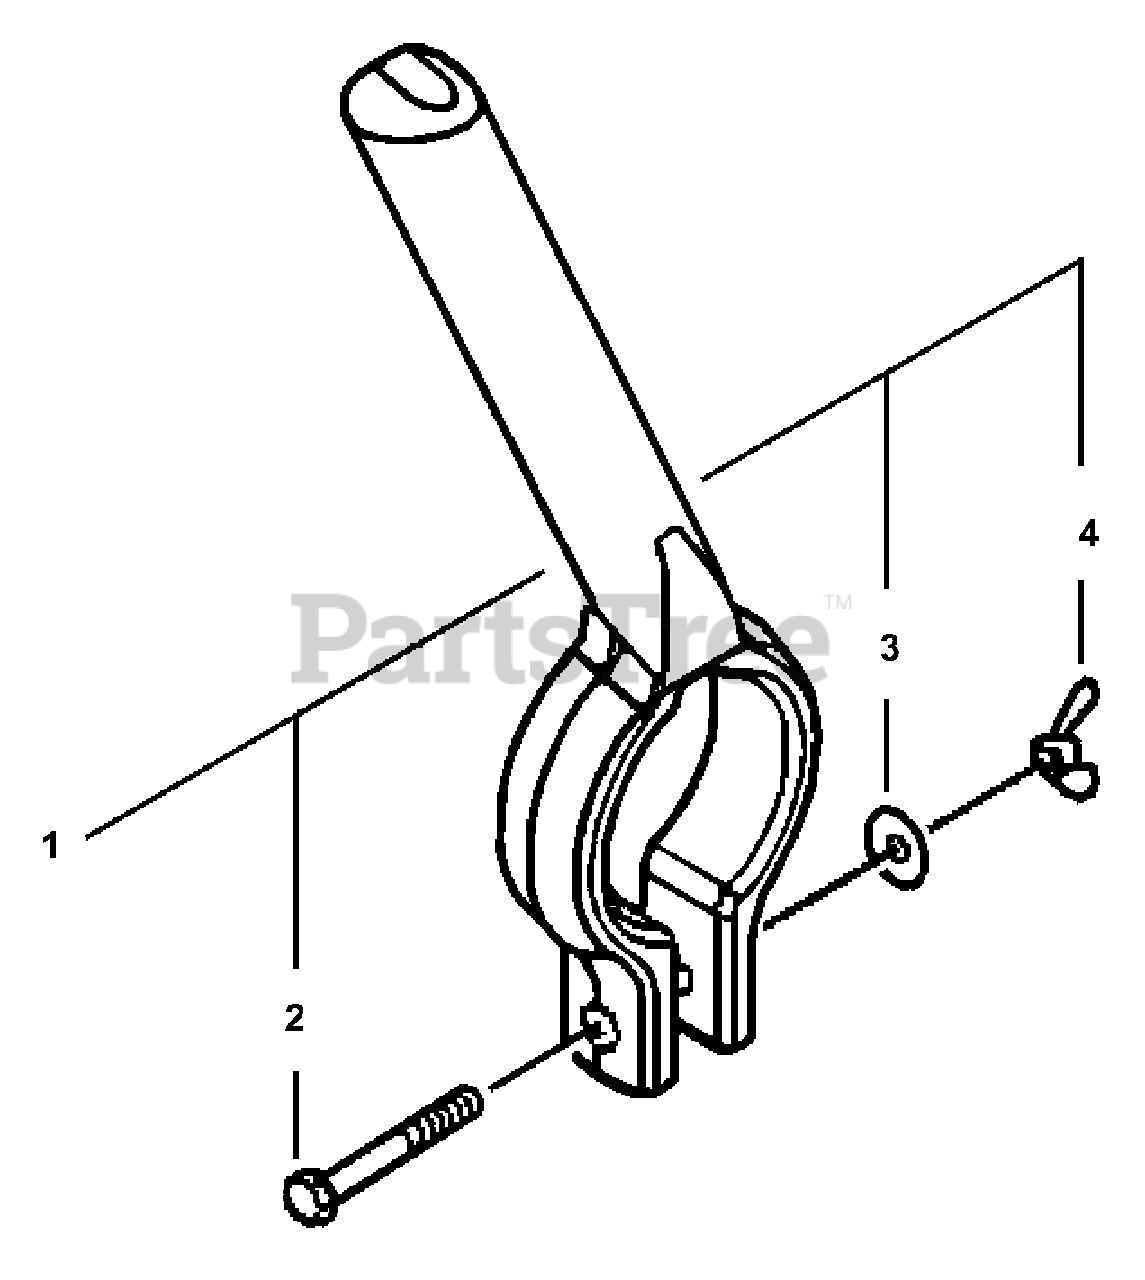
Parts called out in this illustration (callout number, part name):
1	HANDLE ASSY, PB LARGE
2	BOLT 6×45
3	WASHER 6.5×11.5×0.8
4	NUT, WING 6
